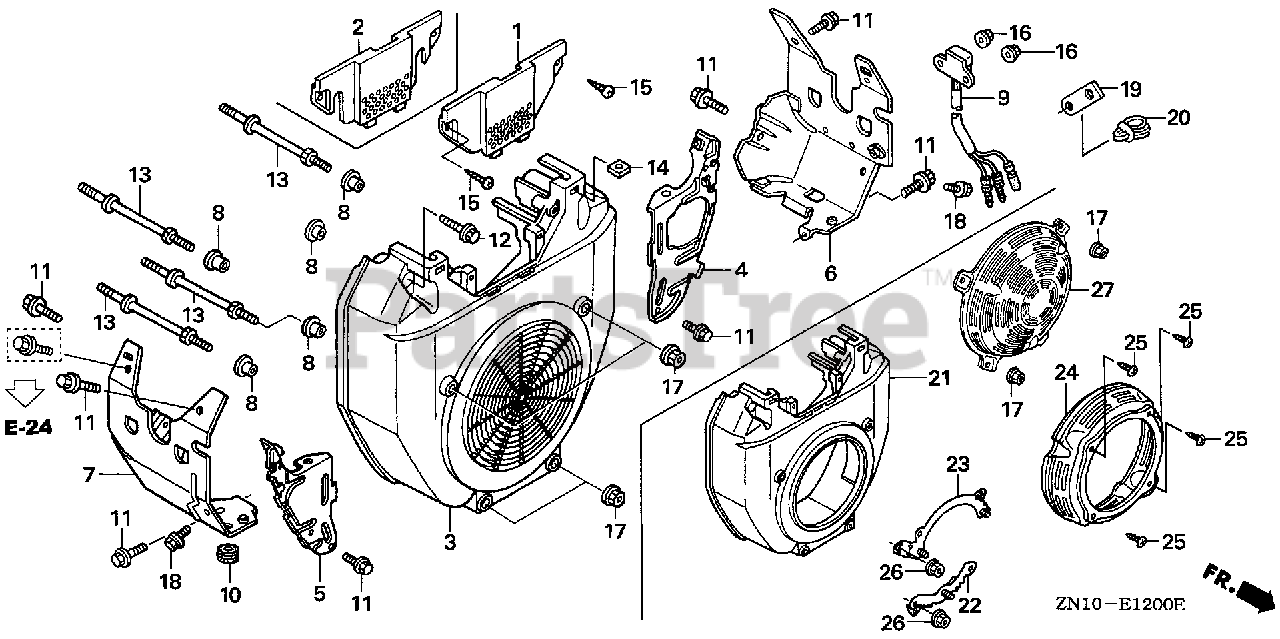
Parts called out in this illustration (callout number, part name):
1	COVER, FUEL PUMP
3	COVER, FAN *NH1* (BLACK)
3	COVER, FAN *R280* (POWER RED)
4	PLATE, SIDE
5	PLATE, SIDE
8	COLLAR B, TAILLIGHT
10	RUBBER, RR. FENDER CUSHION
11	BOLT, FLANGE (6X12) (CT200)
12	BOLT, FLANGE (6X23) (CT200)
13	BOLT, STUD (6X71)
14	NUT, SQUARE (5MM)
15	SCREW, TAPPING (5X20)
17	NUT, FLANGE (6MM)
18	BOLT, FLANGE (6X8)
